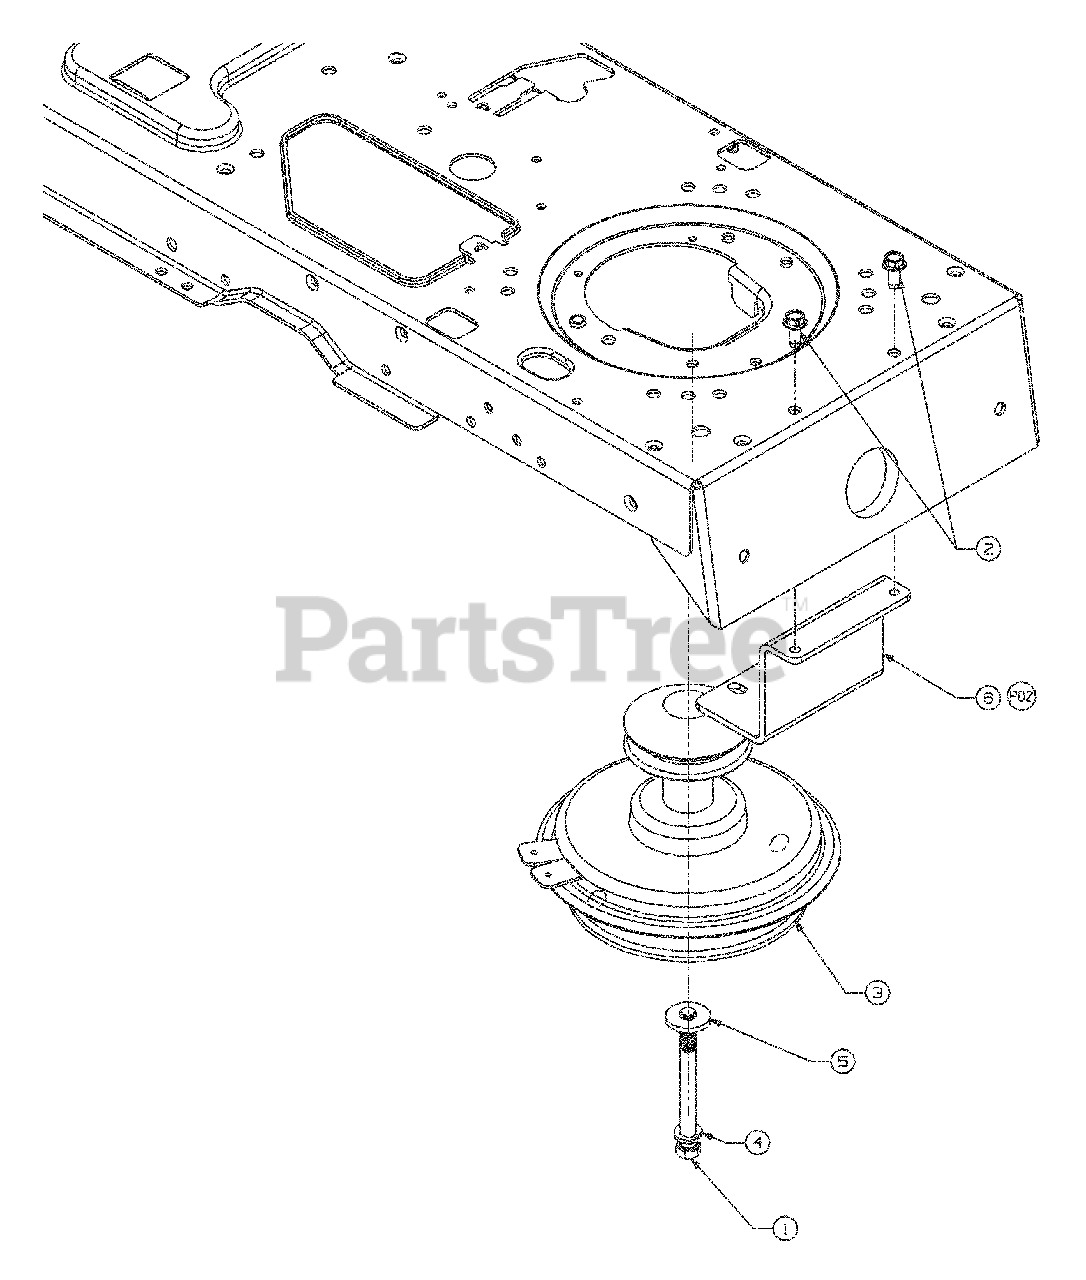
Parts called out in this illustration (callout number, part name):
1	HHCS:7/16-20:4.50:GR5:STD
2	SCR:LD:5/16-18:0.750:HXINDWSH
3	CLU:HYDRO:BRC
4	WASH:LOCK: 7/16 : REGULAR DUTY
